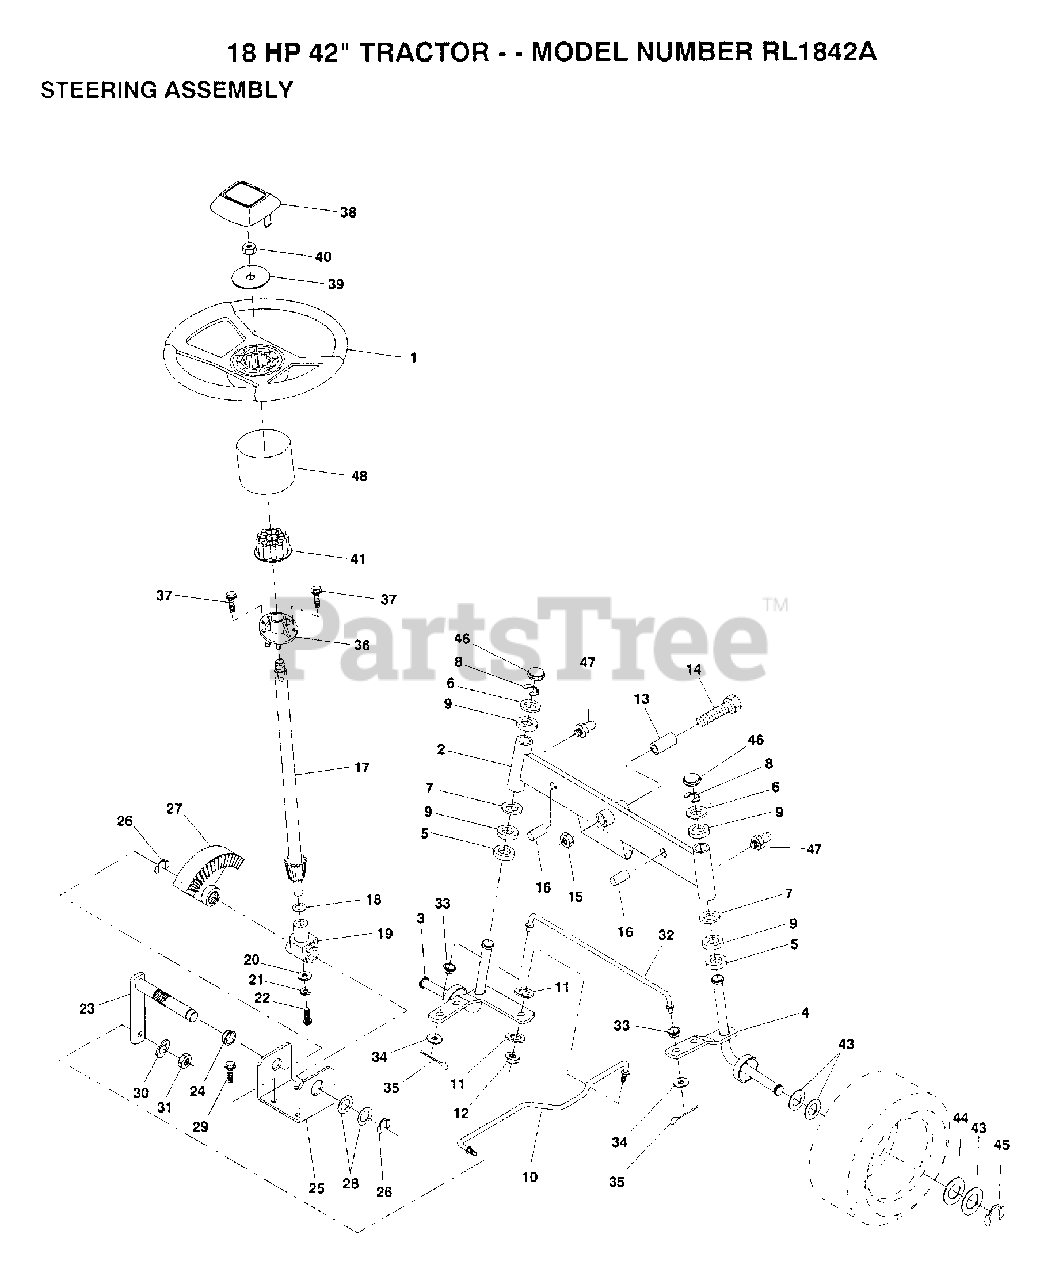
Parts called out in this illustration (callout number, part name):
3	SPINDLE LH
4	SPINDLE RH
5	WASHER .T
6	WASHER
7	WASHER
8	RING
9	COL. SRTG. BEAR.
11	LOCKWASHER
13	BEARING
14	BOLT HEX 5/8-11
15	"NUT-LOC,FLANGE LT"
16	AXLE PIN
17	SHAFT&GEAR STR T
18	THRUST WASHER
19	SUPPORT.SHAFT
21	LOCKWASHER
22	"SCREW,SPECIAL"
24	NYLINER T
25	"BRKT,STEERING"
26	RING
27	GEAR SECTOR
28	WASHER .T
29	SCREW
30	LOCKWASHER
32	TIE ROD
33	BUSHING.DRAGLINK
34	WASHER
35	COTTER PIN
38	ST WHL INSERT CAP
39	WASHER
41	ADAPTER LT
43	WASHER
44	WASHER
45	RING
46	CAP
47	ZERK M
48	SLEEVE LTV
